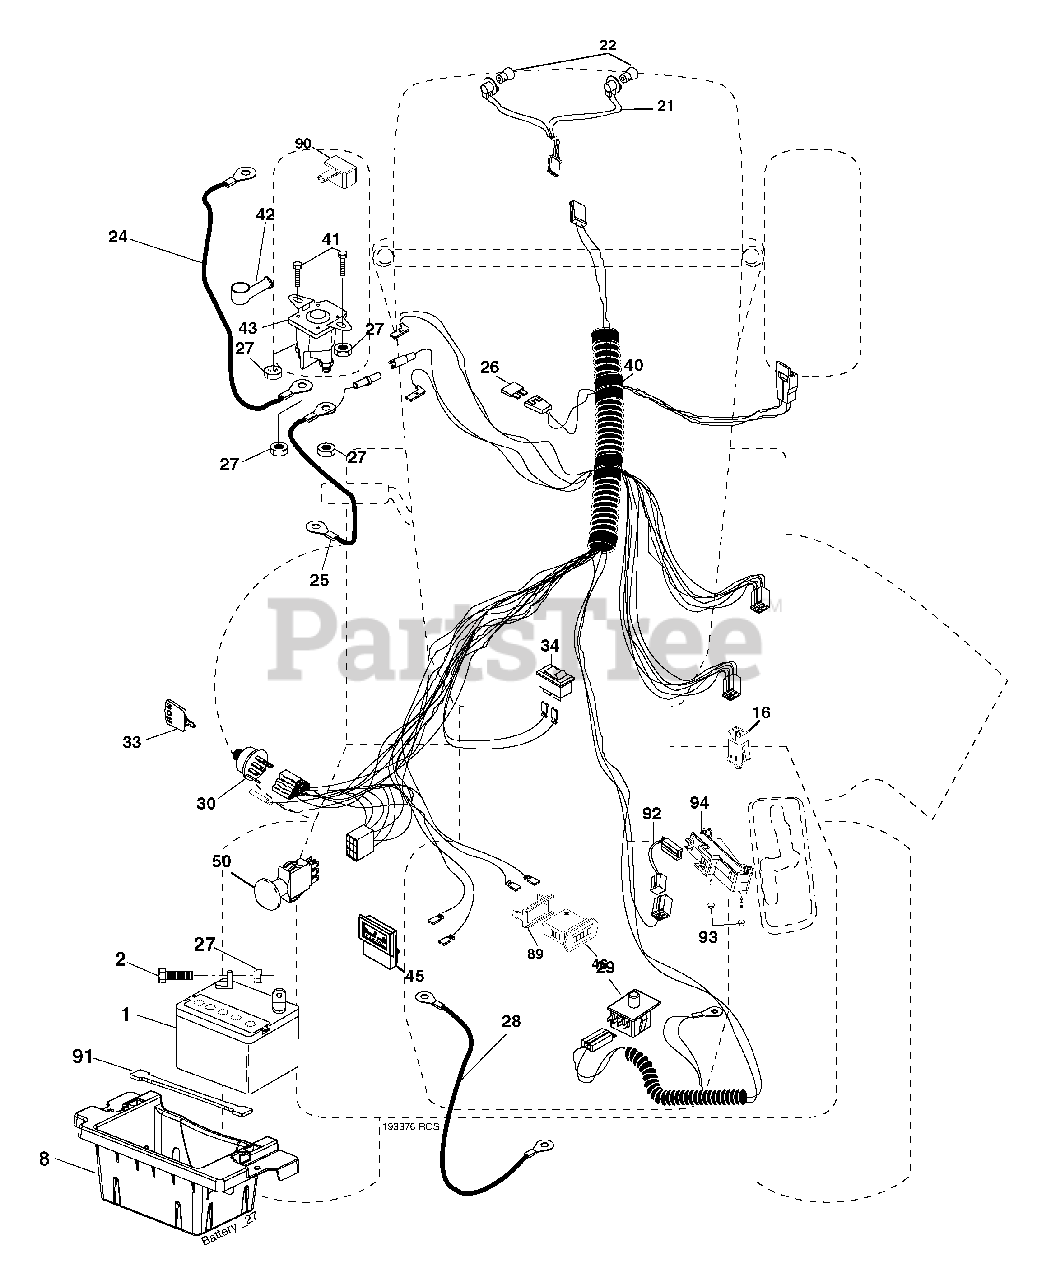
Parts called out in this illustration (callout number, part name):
1	Battery
2	Bolt Hex Hd 1/4-20 unc x 3/4
8	Cable Starter
16	Switch Interlock Push-In
21	Harness Asm Light W/Bulbs
22	Bulb Light
24	Cable Starter
25	Cable Battery
27	Nut Keps Hex 1/4-20 unc
28	Cable Ground
29	Switch Seat
30	Switch Ign
34	Switch Light/Reset
40	Harness Ign.
41	Bolt 1/4-20 x 1/2
42	Cover Terminal
43	Solenoid
45	Ammeter Rectangular
46	Hourmeter Snap-In
50	Switch, PTO
55	Screw Thdrol 5/16-18 x 1/2
89	Bracket Snap-In Hourmeter
90	Cover Terminal Battery
91	Strap Battery
92	Harness Pigtail Reverse Switch
93	Screw Plastite 10-1/4 x 2.0
94	Module Reverse Switch
